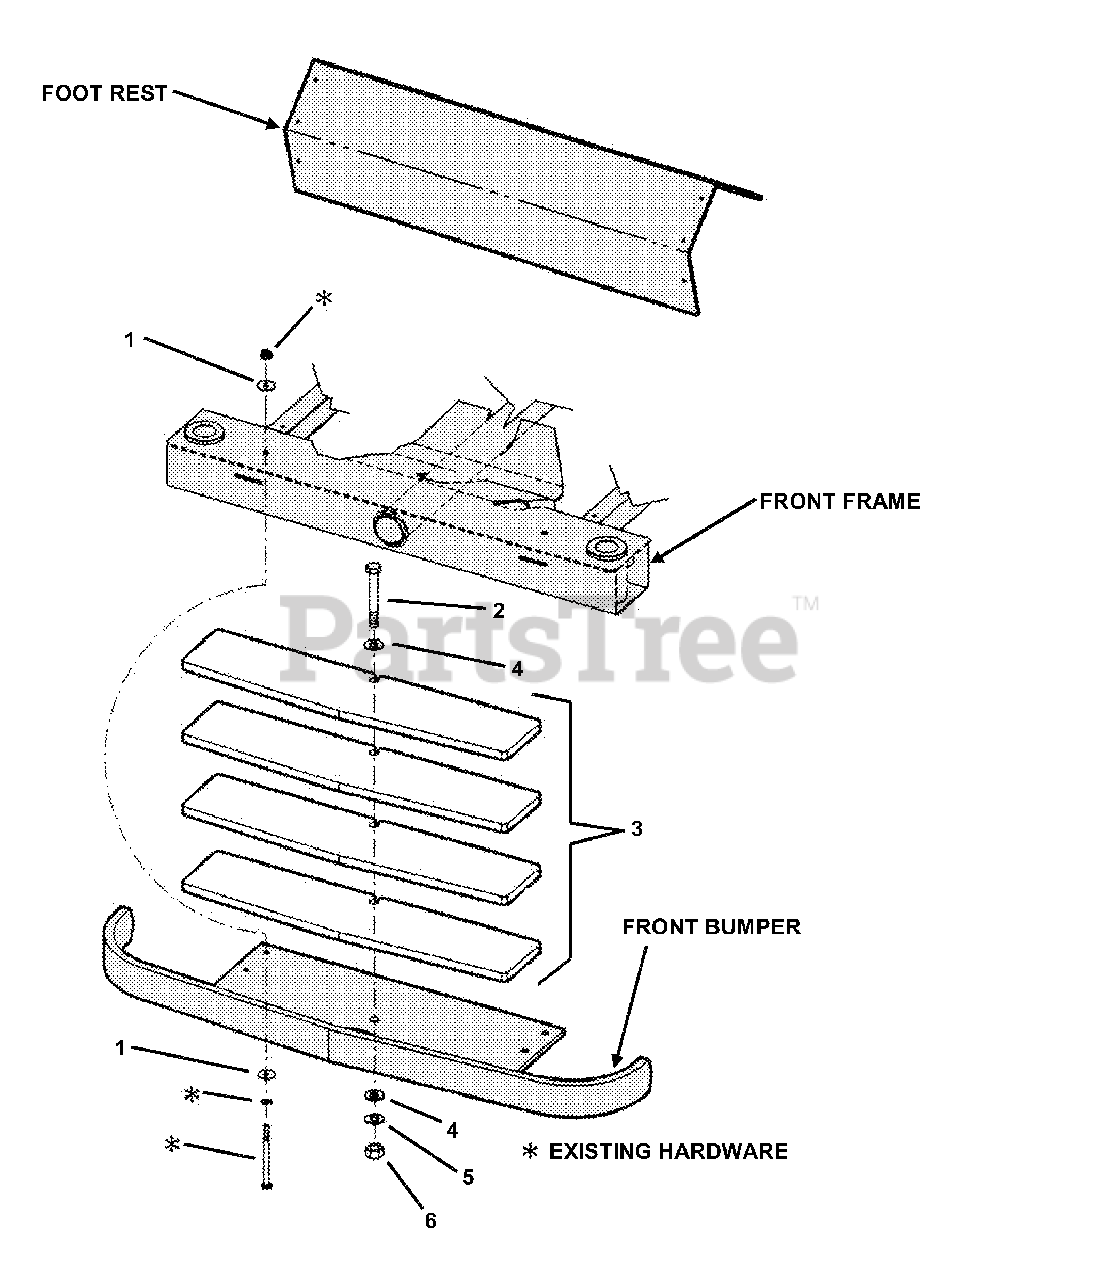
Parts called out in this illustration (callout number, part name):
1	WASHER, 5/16" Fender
2	SCREW, 1/2-13 x 3-1/4" Hex Head Cap, Grade 5
3	WEIGHT, Ballast
4	WASHER, 1/2" SAE
5	WASHER, 1/2" Split Lock
6	NUT, 1/2-13 Hex, Grade B
